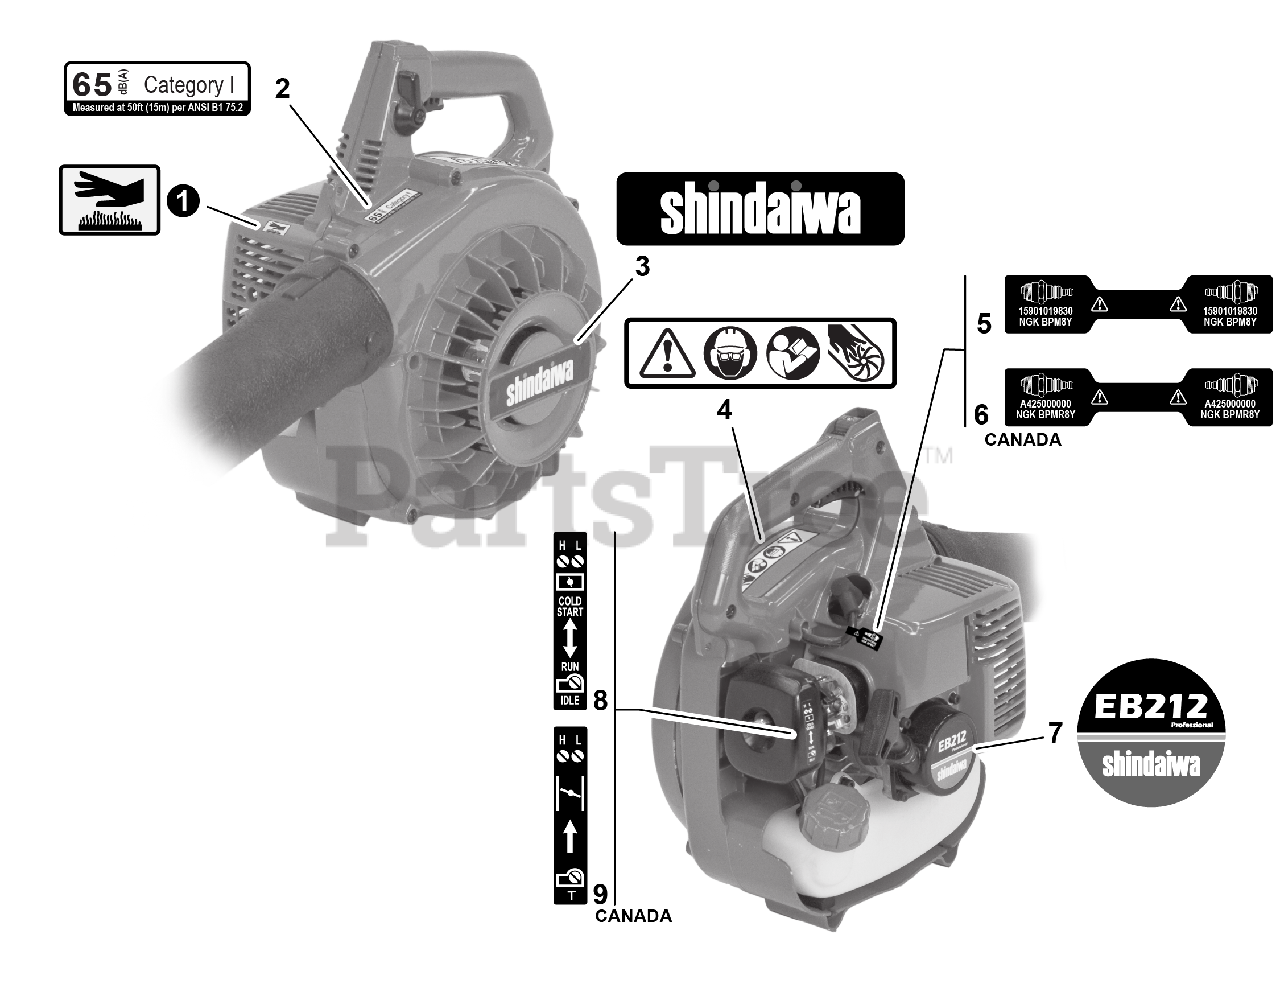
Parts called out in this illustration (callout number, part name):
1	LABEL, CAUTION - HOT
2	LABEL, NOISE
3	LABEL, MODEL
4	LABEL, CAUTION - ISO
5	LABEL, SPARK PLUG - BPM8Y
6	LABEL, SPARK PLUG - BPMR8Y
7	LABEL, MODEL
8	LABEL, CHOKE
9	LABEL, CHOKE
